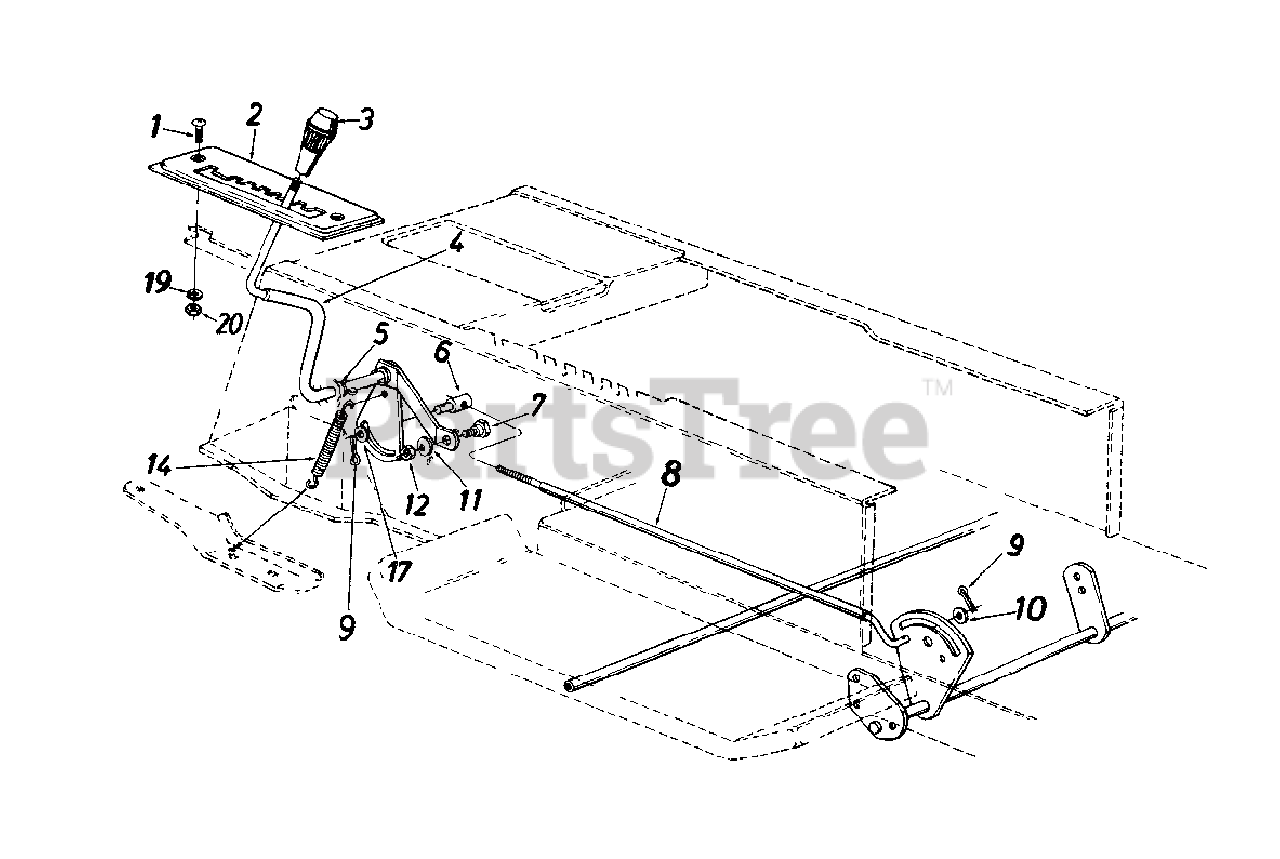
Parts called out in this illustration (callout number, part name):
1	Truss Mach. Scr. 1/4-20 x.75"
4	Speed Selector Lever Ass'y.
5	Flat Washer .53" I.D. x .93"
6	Ferrule 3/8-24 x .37" Dia.
7	Shoulder Bolt
8	Speed Control Link
9	Cotter Pin 3/32" Dia. x 1.0"
10	Fl-Wash. .469" I.D. x .88"
11	L-Wash. 5/16" I.D.
12	Hex Nut 5/16-18 Thd. (Gr. 5)
14	Spring .38" O.D. x 3.18" Lg.
17	Fl-Wash. .385" I.D. x 7/8"
19	L-Wash. 1/4" I.D.
20	Hex Nut 1/4-20 Thd. (Gr. 5)
